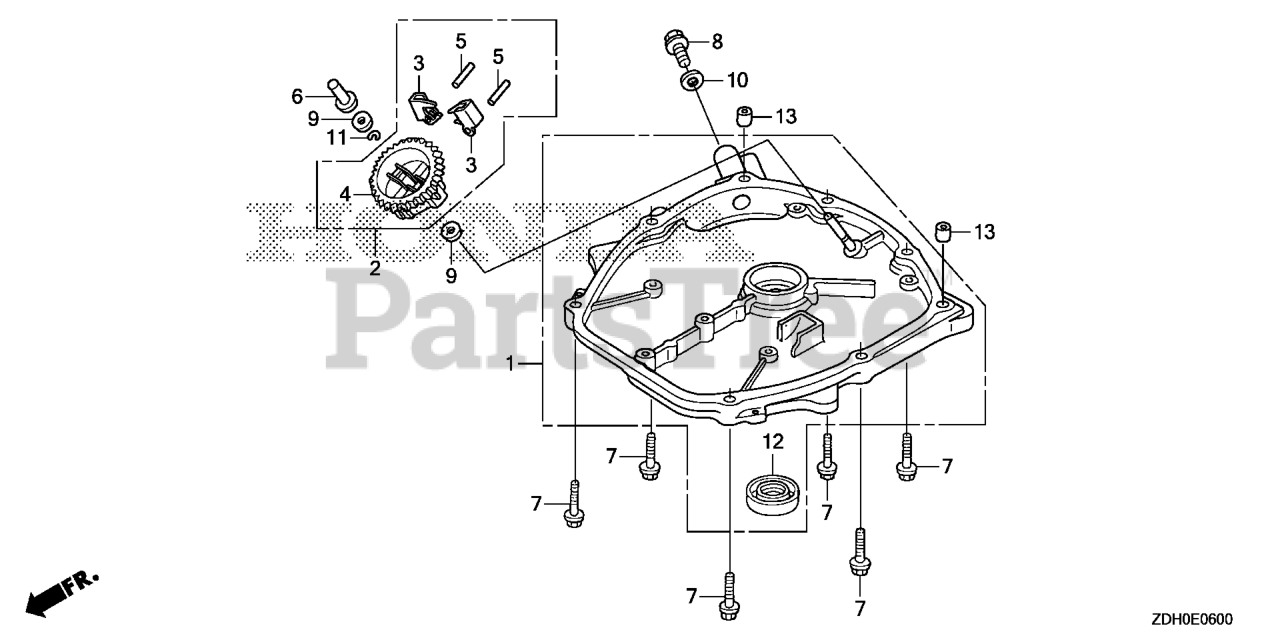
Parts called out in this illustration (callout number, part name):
1	COVER, CRANKCASE SIDE
2	GOVERNOR ASSY.
3	WEIGHT, GOVERNOR
4	HOLDER, GOVERNOR WEIGHT
5	PIN, GOVERNOR WEIGHT
6	SLIDER, GOVERNOR
7	BOLT, FLANGE (5X23)
8	BOLT, DRAIN PLUG
9	WASHER (4.2X13)
10	WASHER, DRAIN PLUG (12MM)
11	CLIP, GOVERNOR HOLDER
12	OIL SEAL (18.9X28X5) (ARAI)
13	PIN A, DOWEL (6X10)
